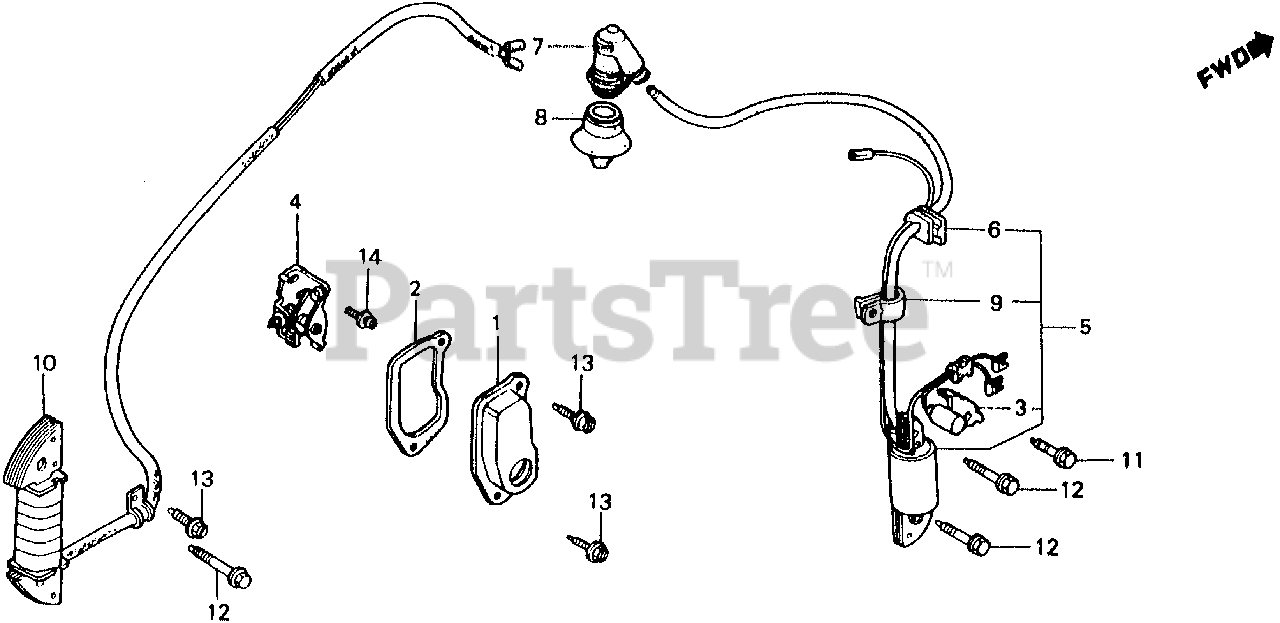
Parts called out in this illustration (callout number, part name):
1	COVER, BREATHER
2	GASKET, COVER
4	POINTS ASSY.
5	COIL ASSY., IGNITION (NOT AVAILABLE)
6	GROMMET, WIRE
7	CAP ASSY., NOISE SUPPRESSOR
8	SEAL, IGNITION
9	CLAMP, IGNITION WIRE
10	COIL ASSY., CHARGE
11	BOLT, FLANGE (6X12) (CT200)
12	BOLT, FLANGE (6X32)
13	BOLT, FLANGE (5X10)
14	SCREW-WASHER (5X12)
